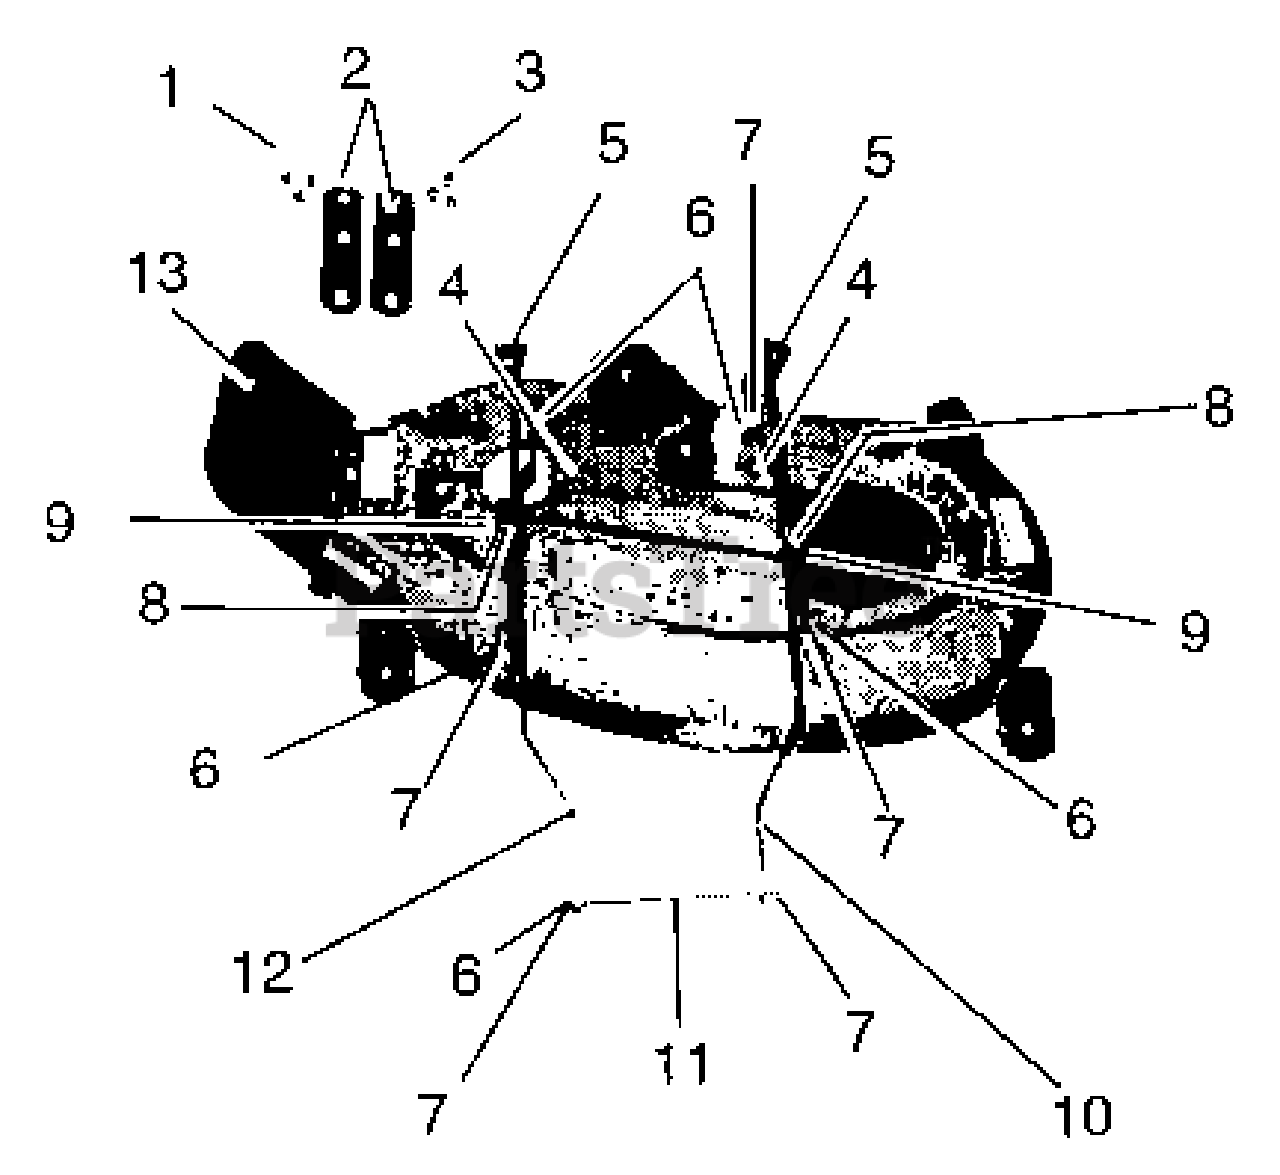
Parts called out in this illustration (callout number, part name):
1	Hex Bolt, 3/8-16 x 3/4
2	Hanger Braket
3	Top Locking Flange nut, 3/8-16
4	Adjuster Link
5	External Hair Pin
6	Spring Clip
7	Flat Steel Washer, 17/32 1-1/16 x 61/64
8	Flat Steel Washer, 21/32 1-5/16 x 61/64
9	Locking Center Nut, 5/8-11
10	Left Lift Assembly
12	Right Lift Assembly
13	40" Deck Assembly (536113)
